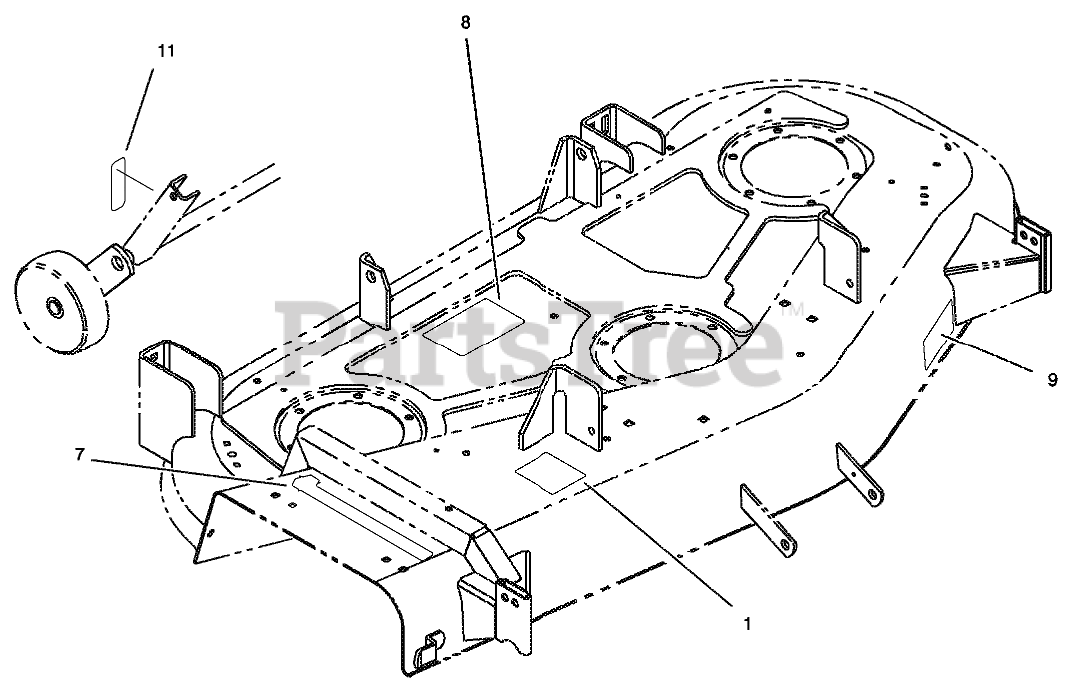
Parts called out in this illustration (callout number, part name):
1	DECAL-BELT ROUTING
7	Decal-Deck (only on: 78375)
8	DECAL-BELT ROUTING
9	DECAL-ADJUSTMENT, WHEEL
11	Decal-HOC (only on: 78370, 78375)
